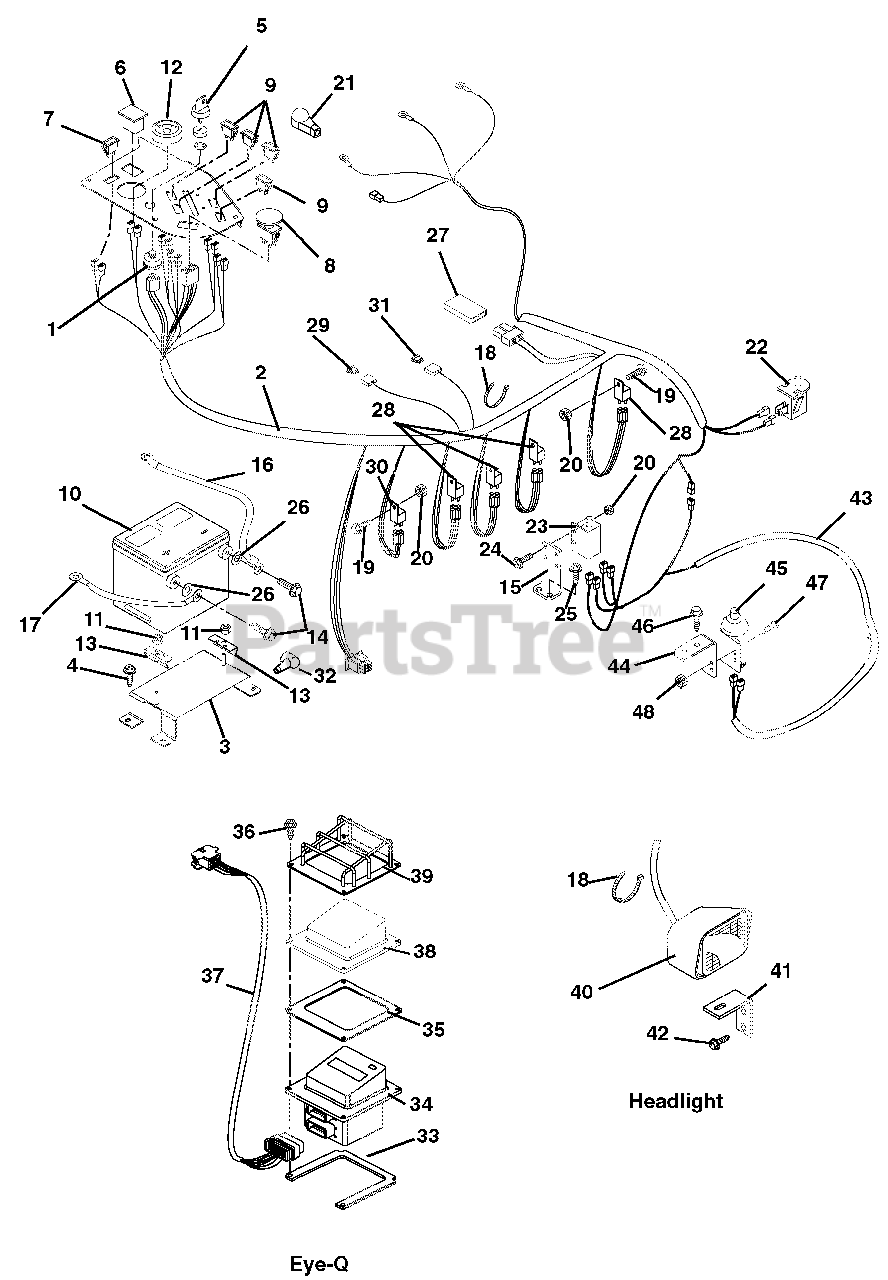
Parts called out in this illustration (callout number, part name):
1	Switch, Ignition
2	Harness, Wiring
3	Weldment, Battery Support
4	Screw-Tapping .38-16 x .75 Hex Washer Head
5	Key-with Cap
6	Hour Meter
7	Switch, Light
8	Switch-Clutch With Retainer Ring
9	Light-Indicator
10	Battery with Tube
11	Nut-Locking-Top-Flange .31-18
12	Gauge, Temperature
13	Bracket, Battery Hold-Down
14	Bolt-Hex .25-20 x .75 Grade 5
15	Mount, Safety Switch
16	Positive Cable w/Boots
17	Cable, Negative Battery
18	Cable Tie
19	Screw-Machine 10-24 x .75 Hex Washer Head
20	Nut-Locking-Nylon 10-24 With Insert
21	Boot, Terminal, Red
22	Switch, Snap Mounting (N.O.) (Included with Seat)
23	Switch-Single Pole
24	Screw-Machine 10-24 x .75 Hex Washer Head
25	Screw-Tapping .25-20 x .50 Hex Washer Head
26	Washer-Flat-Steel .406 x 1.00 x ..083
27	Diode, Connector Shell
28	Relay (Included with Harness)
29	Fuse, ATO 30 Amp (Included with Harness)
30	Pre-Heat Timer (Included with Engine)
31	Fuse, ATO 60 Amp (Included with Harness)
32	Battery Terminal Boot, Red
33	Spacer, Enclosure Mounting (Bottom)
34	Assembly, Eye-Q - Enhanced
35	Gasket, Eye-Q
36	Screw, Machine 10-24 x 1.0 Slotted Pan Black
37	Harness Jumper (Eye-Q)
38	Guard, Element
39	Guard, Eye-Q
40	Headlight
41	Bracket, Headlight Mounting
42	Screw, Tapping, .38-16 x .50 Hex Washer Head
43	Harness, Wire Adapter, CE
44	Switch, Mount
45	Switch, Single Pole (N.O.) with Cover
46	Screw,Tapping .31-18 x .50 Hex Washer Head
47	Screw, Machine 10-24 x .75 Hex Washer Head
48	Nut, Locking, Nylon 10-24 with Insert
